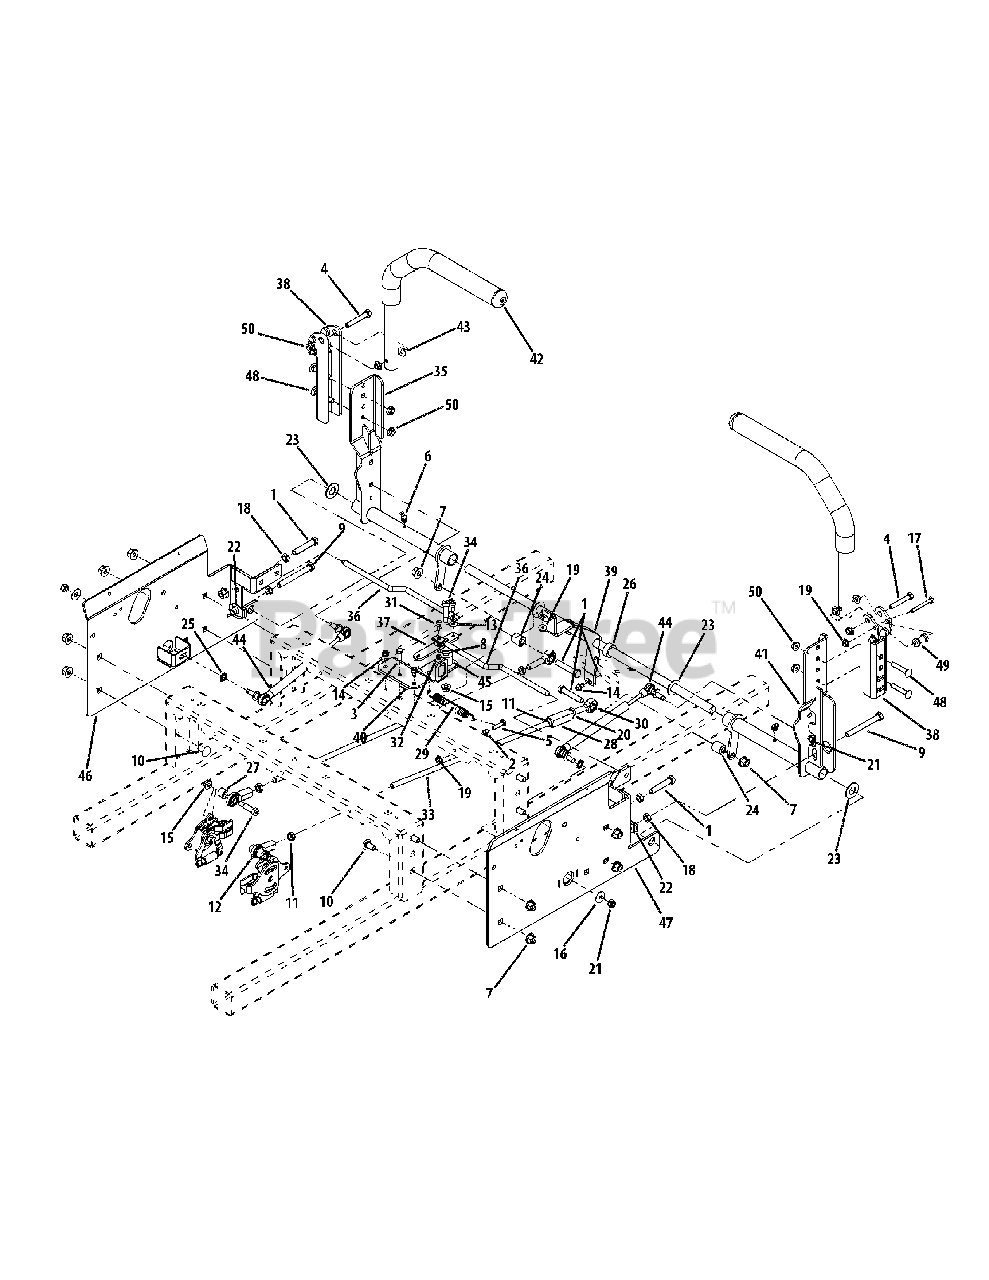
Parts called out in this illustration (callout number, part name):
1	Hex Cap Screw, 3/8-16 x 2.00
2	Hex Nut, 1/4-20
3	Hex Cap Screw, 1/4-20, .75
4	Hex Cap Screw, 5/16-18 x 2.00
5	HHCS, 1/4-20 x 1.00
6	Grease Fitting, 1/4-28, 45 degree
7	Hex Nut, 3/8-16, Lock Flange
8	Washer, 3/8, SS
9	Hex Cap Screw, 3/8-16 x 3.50
10	Carriage Bolt, 3/8-16 x .75
11	Hex Jam Nut, 3/8-24
12	B/Joint, 3/8-24, Right Hand Female
13	Flat Washer, 1.4 x .630 x .0515
14	Screw, TT, 1/4-20, 0.5, Hex Washer
15	Nut, Lock, HexFlange, 5/16-18
16	Belle Washer, .325 x .930 x .045
17	Hex Cap Screw, 1/4-20 x 2.00
18	Nut, 3/8-16, Jam
19	Hex Flange Lock Nut, 1/4-20
20	Nut, 3/8-24, Jam, LH Third
21	Nut, Hex, Center Lock, M8
22	U-Nut, 3/8-16, .75
23	Flat Washer, 5/8 Nylon
24	Spacer, .385 ID x .75 OD x .875
25	External Washer, 3/8
26	Shaft Collar
27	Spacer, .625 OD x .385 ID x 1/2
28	Turnbuckle
29	Extension Spring, .53 OD x 4.75
30	B/Joint, 3/8-24, Left Hand Female
31	Shoulder Bolt, 1/4 x 1/4
32	Nut w/ Star Washer, 10-24
33	Control Rod, 3/8 x 17.312
34	Screw, Shoulder Control Rod
36	Brake/Control Rod
37	Lapbar Control Arm
38	Lapbar Pivot Bracket
39	Lapbar Control Shaft Assembly
40	Lapbar/Brake Control Mounting Brkt.
42	Lapbar Assembly includes:
42	Grip, 1.0
43	Bushing, .310 x .172 x .688 x .06
44	Cylinder Return to Neutral
45	Spacer, .405 ID x 1.0 OD x .72
46	Side Panel, Control, Left
47	Side Panel, Control, Right
48	Carriage Bolt, 5/16-18 x 1.75
49	Spacer, .251 ID x .38 OD x 1.13 LG
50	Nut, Lock, HexFlange, 5/16-18
